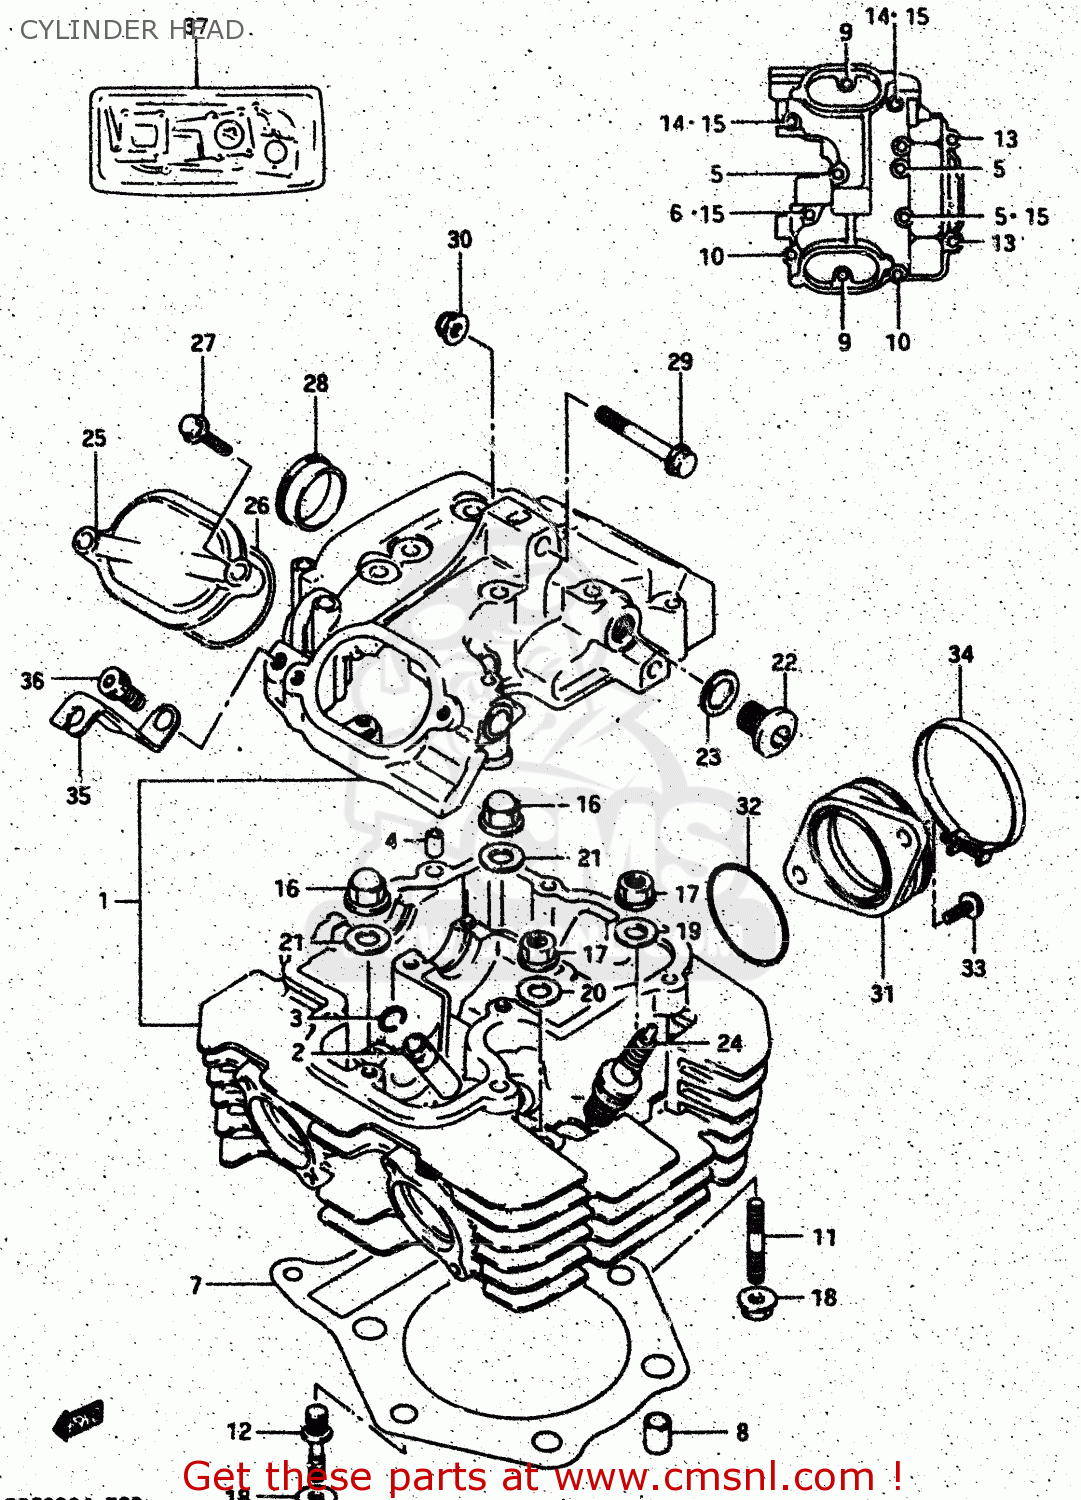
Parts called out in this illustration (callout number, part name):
1	HEAD ASSEMBLY,CYLINDER
2	GUIDE,VALVE
3	RING,SNAP
4	PIN(6.2X8X11)
5	BOLT ,6X60
6	BOLT 6X55
7	GASKET,CYLINDER HEAD (NAS)
8	PIN
9	BOLT
10	BOLT
11	STUD
12	STUD
13	BOLT(6X130)
14	BOLT ,6X60
15	GASKET(5.8X13X1.2) (NAS)
16	NUT
17	NUT
18	NUT 8MM
19	WASHER(10.5X22X2.3)
20	WASHER(10.5X24X2.3)
21	GASKET(10.5X22X2) (NAS)
22	PLUG
23	GASKET(14X19.2X2) (NAS)
24	PLUG,SPARK(DPR9EA-9)
25	CAP,INSPECTION
26	O RING(D:2.4,ID:23)
27	BOLT
28	PLUG(OD:30)
29	BOLT 8X50
30	NUT
31	PIPE,INTAKE
32	O RING(D:2.4,ID:45.7)
33	SCREW
34	CLAMP
35	LEVER,DECOMP SHAFT RH
36	BOLT
37	GASKET SET
